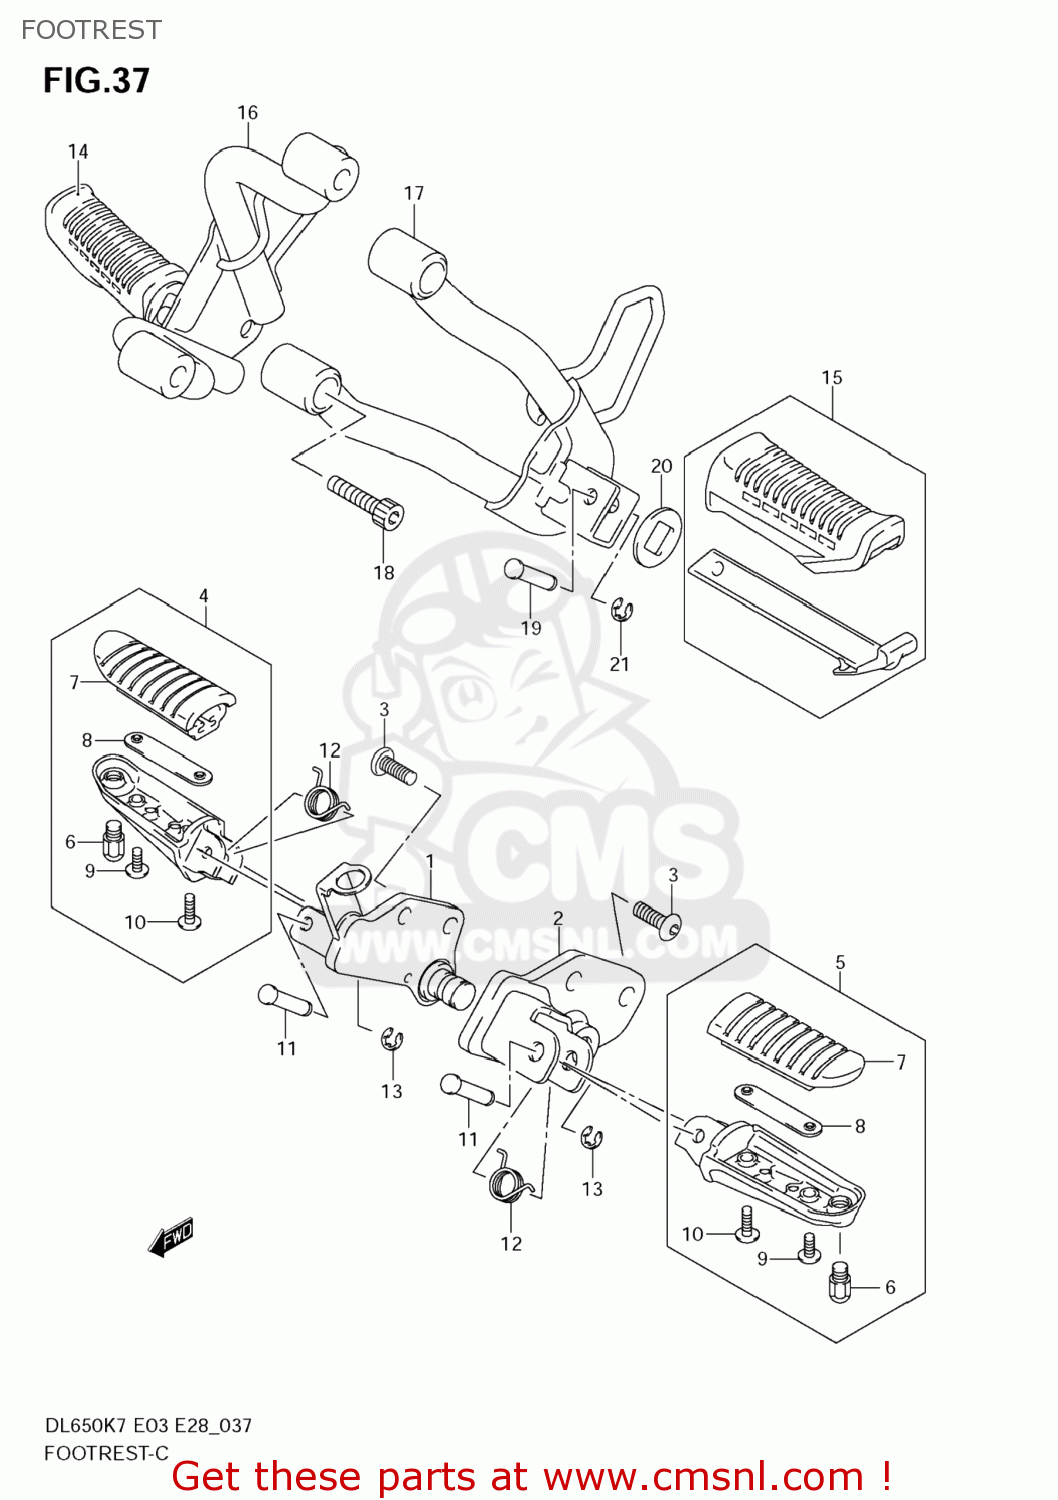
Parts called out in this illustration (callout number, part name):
1	BRACKET,FR FOO
2	BRACKET,FR FOO
3	BOLT(8X23)
4	FOOTREST ASSY,PILLION,R
5	FOOTREST ASSY,PILLION,L
6	BOLT,BANK SENSOR
7	RUBBER,FOOTREST
8	PLATE,FR FOOTREST RUBBER
9	SCREW
10	SCREW
11	PIN(8X33.2)
12	SPRING
13	E RING
14	FOOTREST ASSY,PILLION,R
15	FOOTREST ASSY,PILLION,L
16	BRACKET,PILLION FOOTREST,R
17	BRACKET,PILLION FOOTREST,L(BLA
18	BOLT(8X40)
19	PIN
20	WASHER,FOOTREST RUBBER
21	E RING
